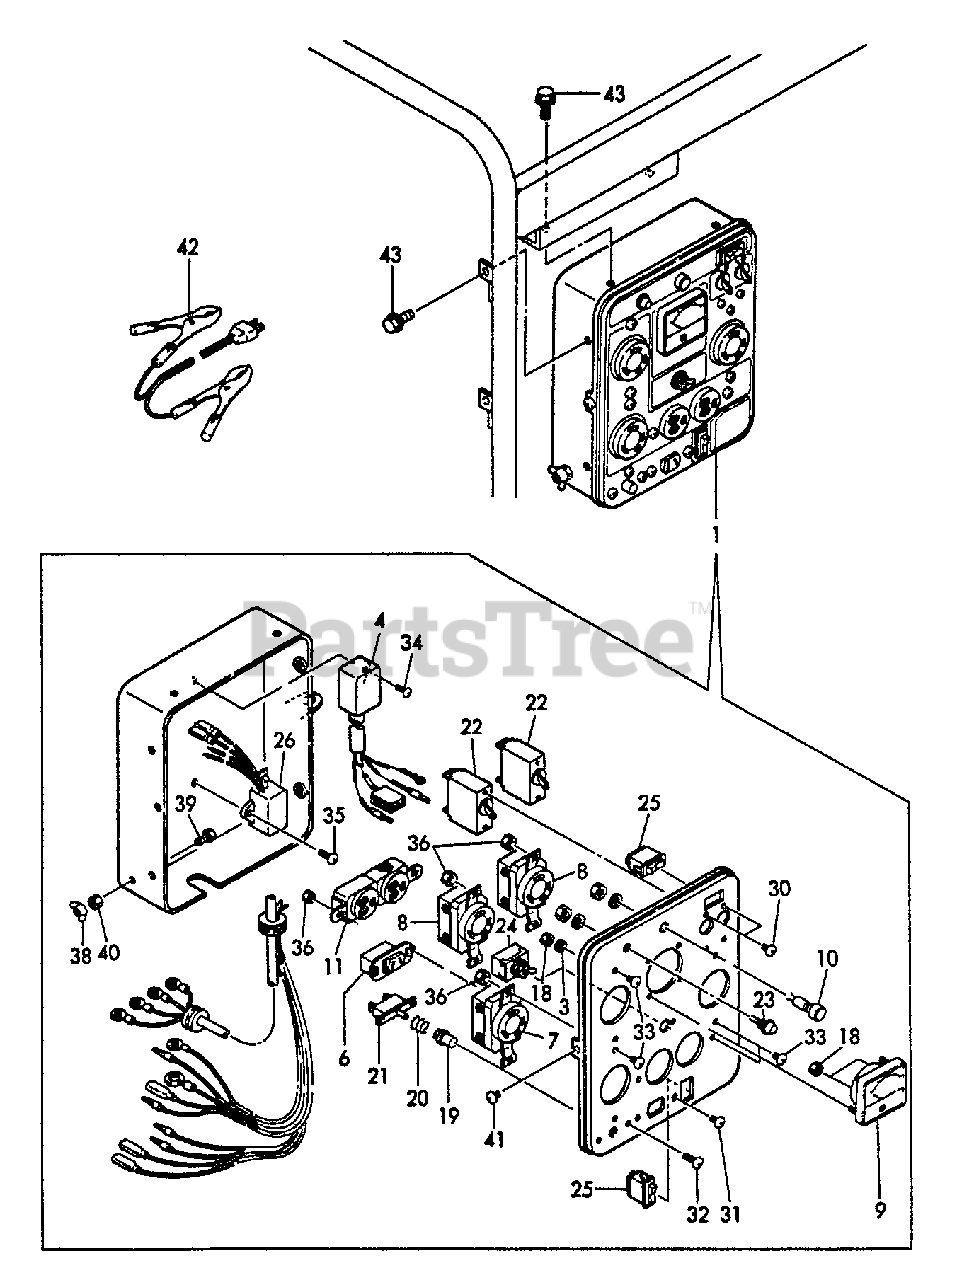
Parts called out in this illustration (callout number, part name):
1	PANEL BOX ASSY
3	WASHER, DECOMP.
4	SENSOR UNIT, OIL
6	DC CONNECT
7	CONNECT
8	CONNECT
9	METER, VOLTAGE - 300V
10	LAMP, PILOT
11	AC CONNECT
18	NUT - 3
19	CAP, BREAKER
20	SPRING BREAKER
21	BREAKER
22	AC BREAKER
23	LAMP, OIL ALERT
24	SWITCH
25	SWITCH
26	UNIT, SLOW-DOWN
30	SCREW - 3×6
31	SCREW - 3×6
32	SCREW 3×12
33	SCREW - 4×6
34	SCREW - 5×10
35	SCREW - 5×10
36	NUT - 4
38	WINGNUT - 6
39	BOLT - 6×16 -- PLATED
40	LOCKNUT - 6 -- PLATED
41	SCREW - 4×6
43	BOLT - 6×8 -- PLATED
